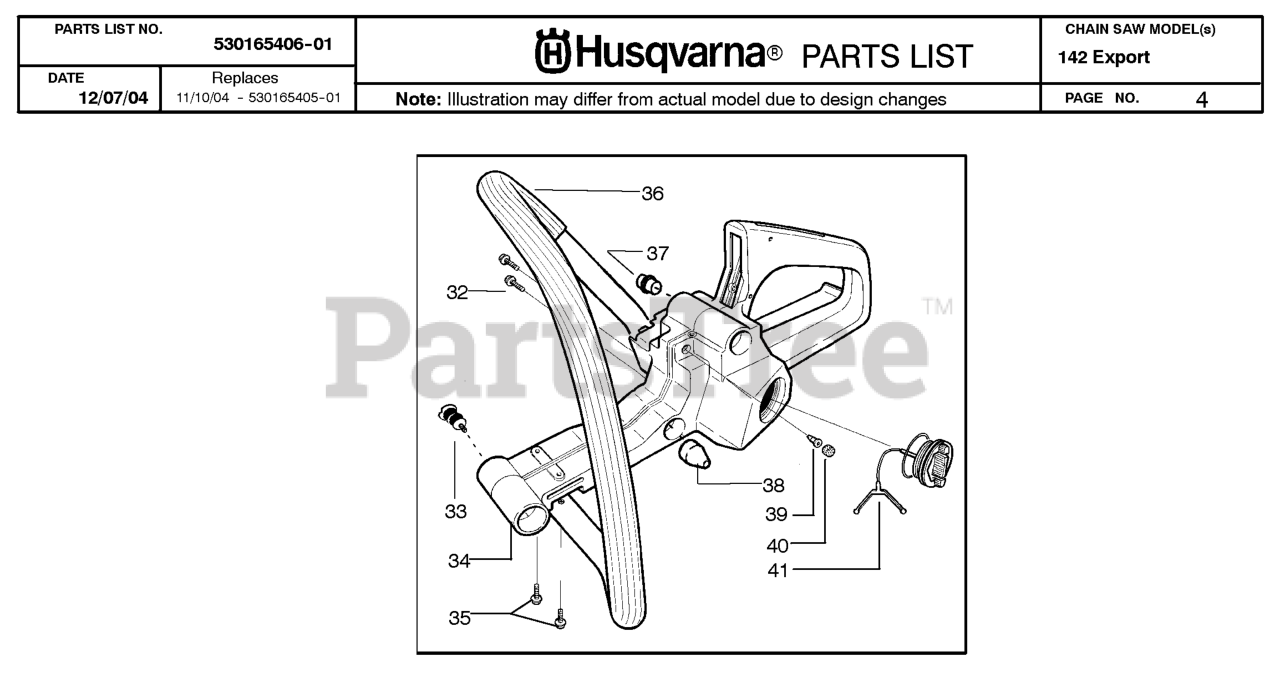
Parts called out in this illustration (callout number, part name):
1	THROTTLE CONTROL
2	SCREW.#10 X 0.750.BOS
4	MUFFLER.TWIN.CYL.LOW.TONE
5	RP.PIPE-EXHAUST LH
6	RP.PIPE-EXHAUST RH
8	BOLT.5/16-18UNCX3/4 W/SEMS.BLK
10	RP SHIELD HEAT MUFFLER
14	TUBE, DRAIN OIL ASM.
23	SHIELD.BROWNING.DBR.GUARD
25	CONTROL, CHOKE
29	KIT.SPARK ARRESTOR 794945 B&S
31	TANK.ASM.FUEL.FR.2.5GA.
32	CAP.FUEL.2.25"VENTED"
33	HOSE CLAMP
37	LINE.FUEL.20
38	PLUG DRAIN OIL EASY
44	SCREW HEXWSHR 1/4-20X3/4
45	SCREW, 3/8-16X3/4
72	SCREW.SOCKET HD.5/16-1
81	NUT
91	BUSHING.1.375OD
105	SCREW 3/8-16X1
